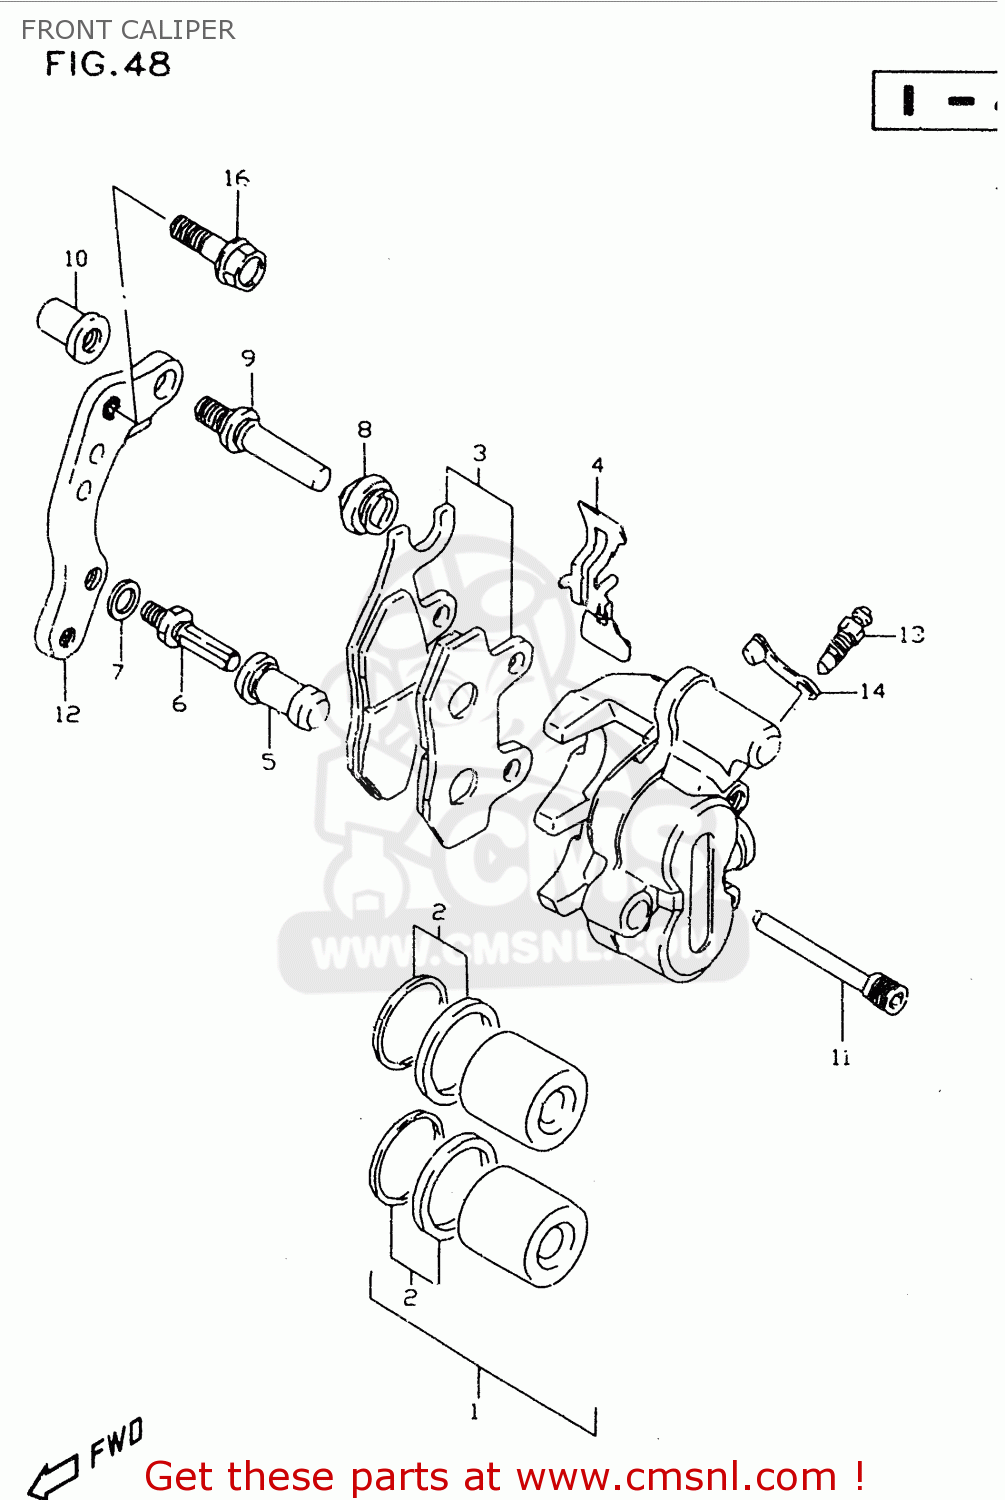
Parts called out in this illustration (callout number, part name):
1	PISTON SET
2	SEAL SET,PISTON
3	PAD SET (NAS)
4	SPRING
5	BOOT
6	BOLT,PIN
7	WASHER,WAVE
8	BOOT
9	PIN,SLIDE
10	NUT
11	PIN,HOLDER
12	BRACKET
13	BLEEDER
14	CAP,BLEEDER
15	BOLT(8X24)
